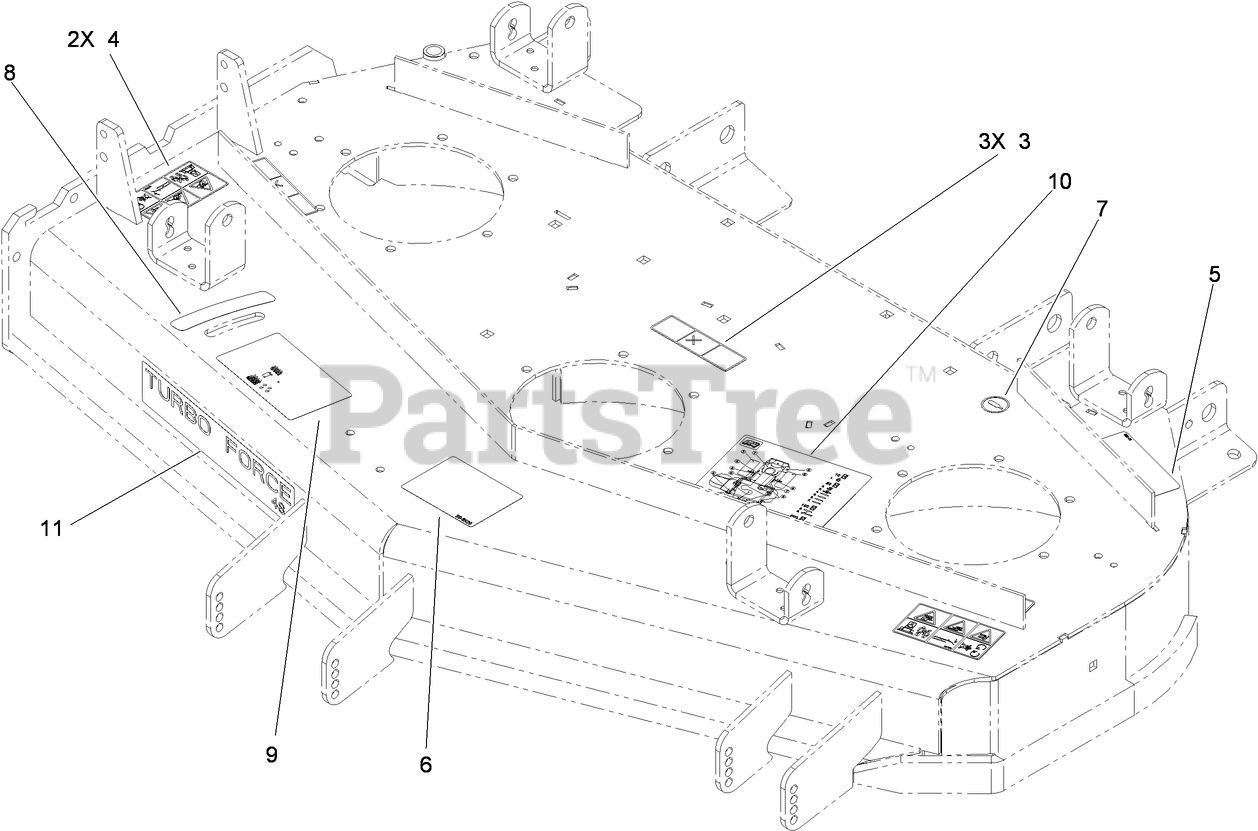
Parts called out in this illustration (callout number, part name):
3	DECAL-MISSING, COVER
4	DECAL-DANGER
5	DECAL-TORQUE, BLADE BOLT
6	DECAL-ANTI SCALP
7	DECAL-GREASE
8	DECAL-SETTING, BAFFLE
9	DECAL-ADJUSTMENT, BAFFLE
10	DECAL-SERVICE AID
